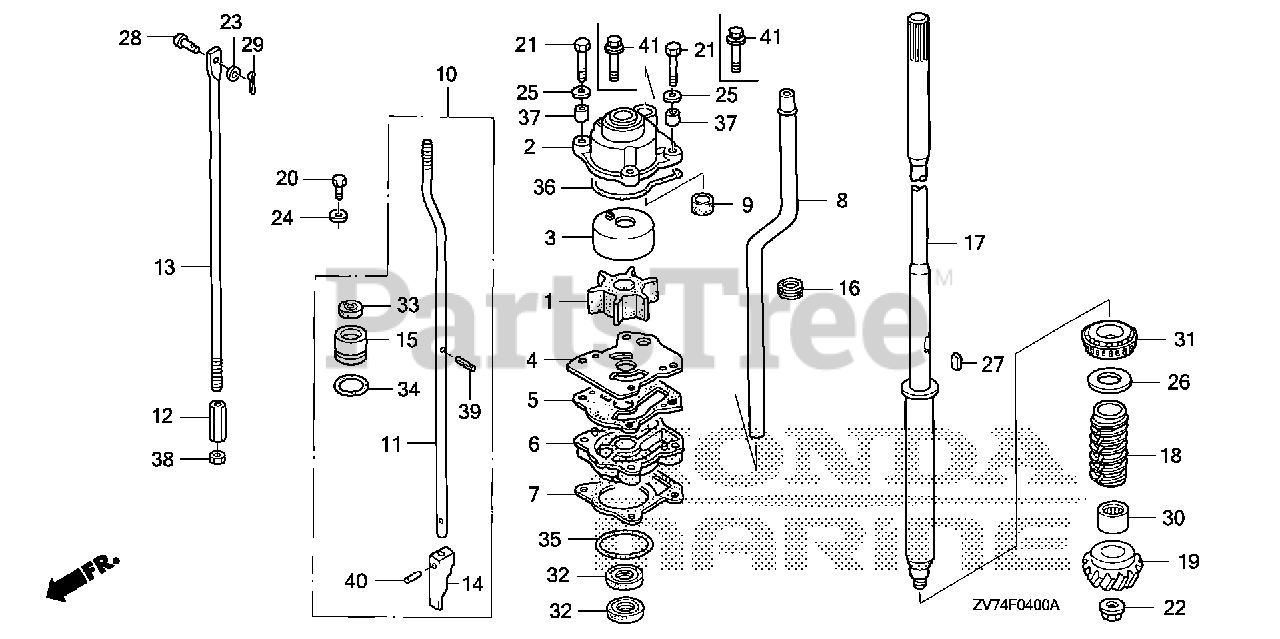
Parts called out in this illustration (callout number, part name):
1	IMPELLER, PUMP
2	HOUSING, IMPELLER
3	LINER, PUMP
4	COVER, IMPELLER
5	GASKET B, IMPELLER
6	HOUSING, WATER PUMP
7	GASKET, WATER PUMP
8	TUBE, WATER (S)
9	RING, WATER TUBE SEAL
10	ROD, SHIFT (S)
11	ROD B, SHIFT (S)
12	JOINT, SHIFT ROD
13	ROD A, SHIFT
15	HOLDER, SEAL
16	GROMMET, EXTENSION CASE
17	SHAFT, VERTICAL (S)
18	SLINGER, OIL
20	BOLT, HEX. (6X12)
21	BOLT, HEX. (6X40)
22	NUT, SPECIAL (10MM)
23	WASHER, PLAIN (5MM)
24	WASHER, PLAIN (6MM)
24	WASHER, SPECIAL
25	WASHER (6MM)
26	SHIM, GEAR (40X46X0.10) (A)
26	SHIM, GEAR (40X46X0.15) (B)
26	SHIM, GEAR (40X46X0.30) (C)
26	SHIM, GEAR (40X46X0.50) (D)
27	KEY, WOODRUFF (5MM)
28	PIN (5X17)
29	PIN, SPLIT (1.6MM)
30	BEARING, NEEDLE (7/8X11/8X1)
31	BEARING (25X47X15)
32	SEAL, WATER (17X30X7)
33	SEAL, WATER (6MM)
34	O-RING (20.8X2.4)
35	O-RING (41.7X3.5)
36	O-RING, WATER PUMP
37	COLLAR, IMPELLER HOUSING
38	NUT, HEX. (6MM)
39	PIN, SPRING (2X12)
40	ROLLER (2.5X11.8)
41	BOLT-WASHER (6X40)
